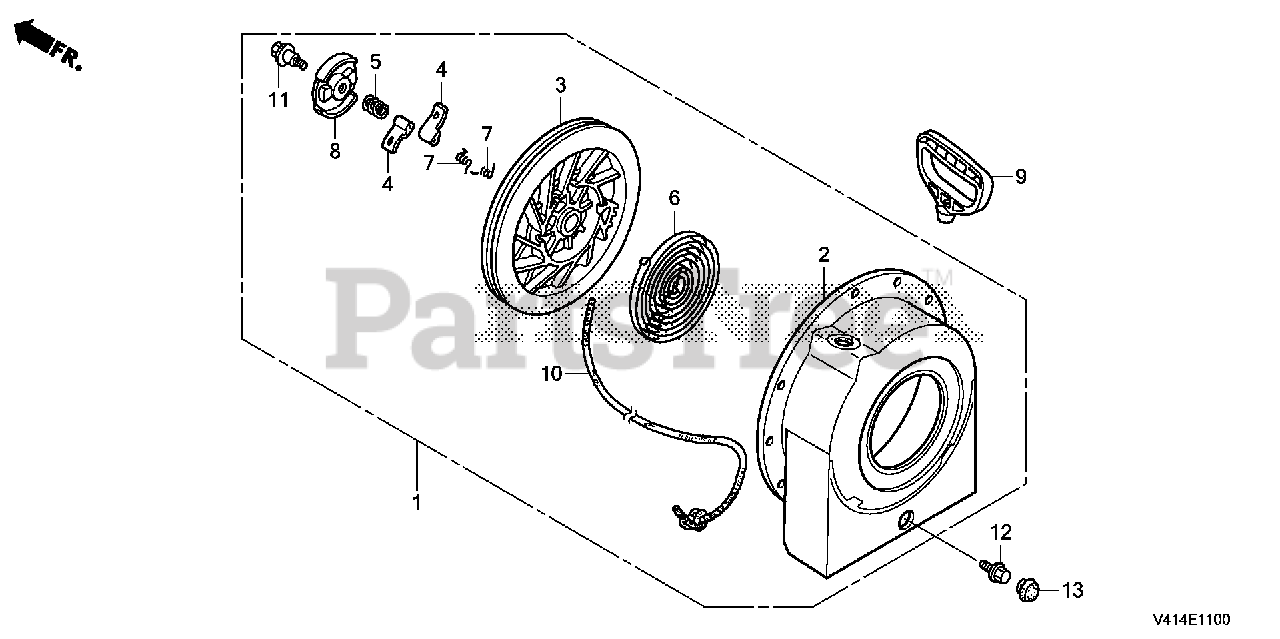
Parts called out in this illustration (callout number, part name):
1	STARTER ASSY., RECOIL *R280* (COO) (POWER RED)
2	CASE, RECOIL STARTER *R280* (POWER RED)
3	PULLEY, RECOIL STARTER
4	RATCHET, STARTER
5	SPRING, FRICTION
6	SPRING, STARTER RETURN
7	SPRING, RATCHET
8	RETAINER, SPRING
9	GRIP, STARTER
10	ROPE, RECOIL STARTER (NA USE ALT:08550-ZG921-11)
11	SCREW, CENTER
12	BOLT, FLANGE (6X10)
13	GROMMET B, CONTROL WIRE
